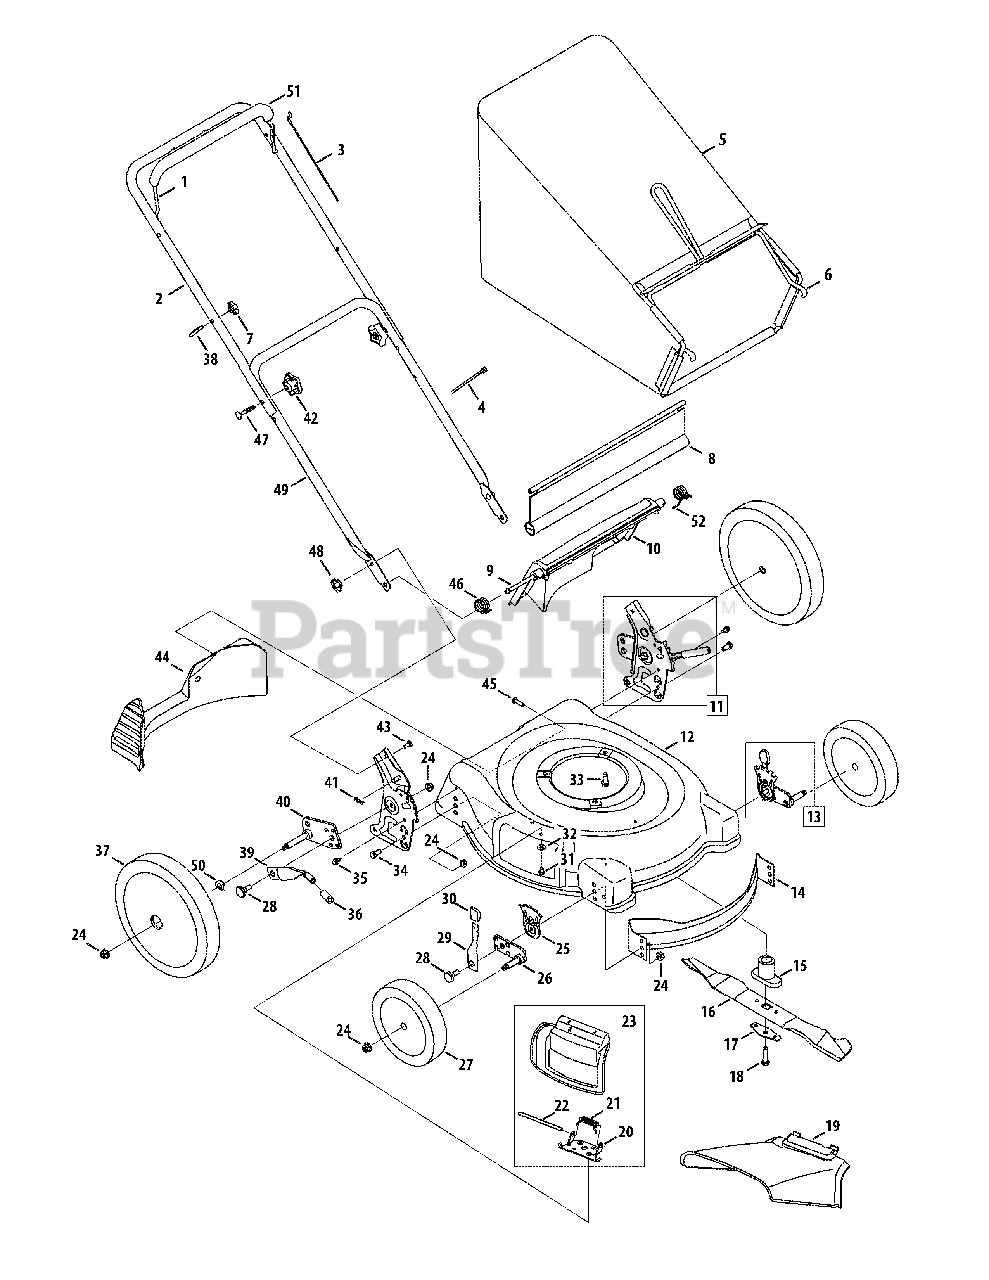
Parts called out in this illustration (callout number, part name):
3	Control Cable, 37.25"
3	Control Cable, 40"
3	Control Cable, 40", Snap-On, Kaw
4	Cable Tie
5	Grass Bag Assembly
7	Handle Knob
8	Trailshield
10	Rear Discharge Door
11	Rear Handle Bracket Assy. - LH
11	Rear Handle Bracket Assy. - RH
13	Front Hgt. Adj. Assy., 8" Whl. - RH
14	Front Baffle
15	Blade Adapter - 25mm
15	Blade Adapter w/Star
16	21-inch Mulching Blade
17	Bell Blade Support
18	Hex Screw, 3/8-24 x 2.5
19	Side Discharge Chute
20	Deflector Chute Adaptor
21	Torsion Spring
22	Hinge Pin
23	Mulch Plug Assembly
24	Flange Lock Nut 3/8-16
25	Height Adjustment Plate
26	Pivot Arm Assy RH (8" wheel)
26	Pivot Arm Assy LH (8" wheel)
27	Front Wheel
28	Shoulder Scr., .5D x .385
29	Front Spring Lever
30	Height Adjust Knob
31	TT Screw, 1/4-20 x .500
32	Bell Washer
33	TT Screw, 3/8-16 x 1.0
34	Hex Screw, 3/8-16 x .75
35	TT Screw, 1/4-20 x .625
36	Foam Grip
37	Rear Wheel
39	Rear Hi-Wheel Spring Lever
40	Rear Pivot Arm Assy - RH
40	Rear Pivot Arm Assy - LH
41	Hairpin Clip
42	Star Knob
43	Carriage Bolt ,1/4-20 x .75
44	Rear Baffle
45	Screw HL, 1/4-15 x 1.00
46	Torsion Spring - RH
47	Carriage Bolt, 5/16-18 x 2
48	Wing Nut
50	Spring Washer
51	Deluxe Bail Cover - Red
52	Torsion Spring - LH
